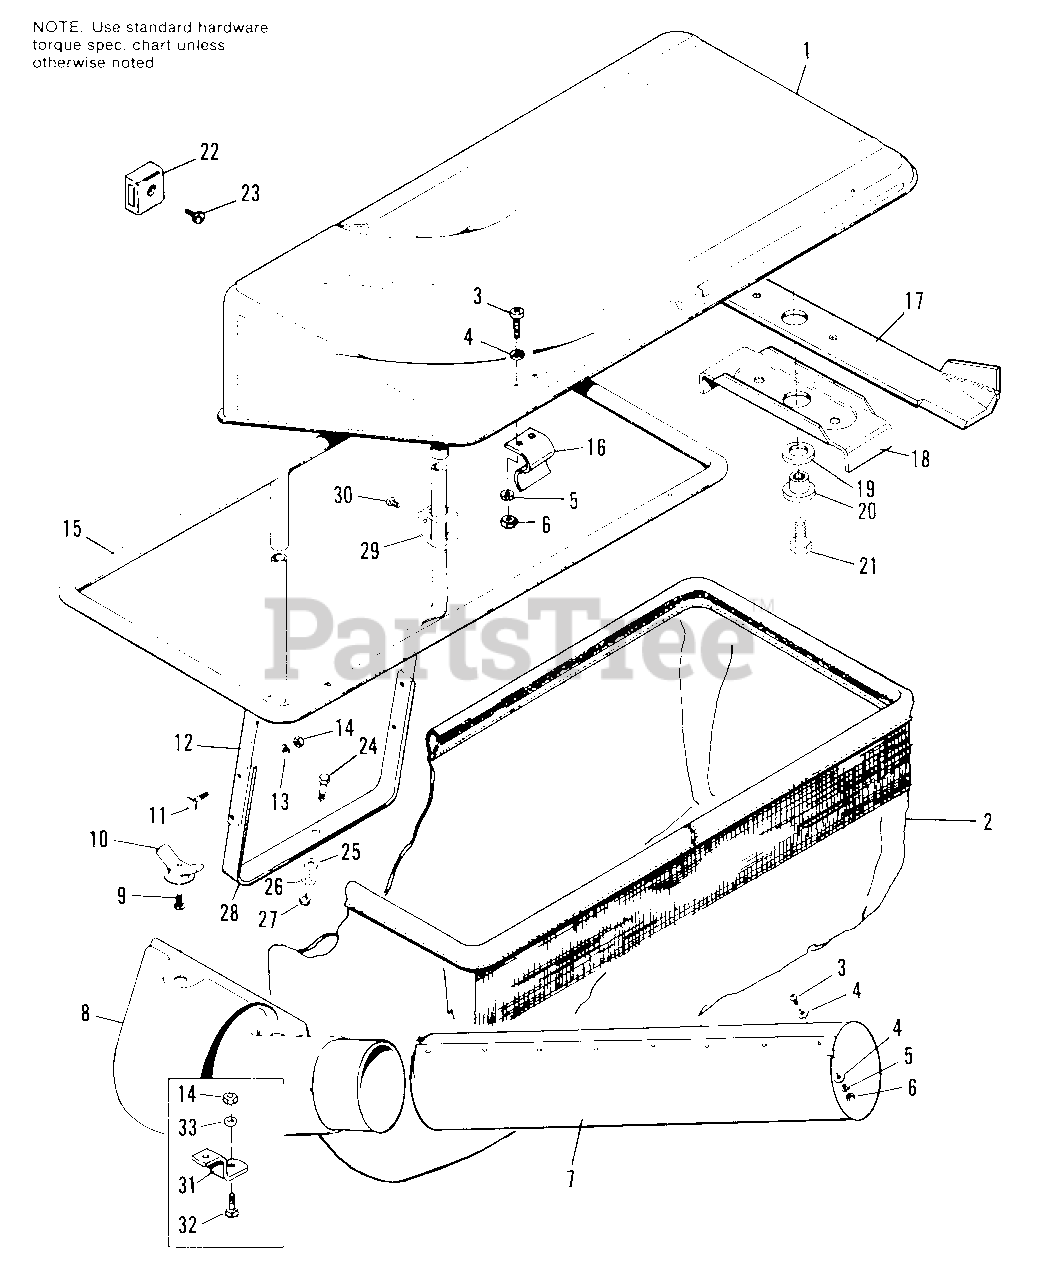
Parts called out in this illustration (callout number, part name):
2	BAG, Grass
3	SCREW, Phillips Hd., #10-32 x 1/2
4	WASHER, Plain, 3/16
5	LOCKWASHER, #10
6	NUT, Hex, Full, #10-32
7	TUBE, Discharge
9	BOLT, Carriage, 5/16-18 x 1
10	NUT ASSY.
11	BOLT, Curved Hd.
12	SUPPORT, Vertical
13	LOCKWASHER, 5/16
14	NUT, Hex, Full, 5/16-18
15	BRACKET, Support
17	*BLADE ASSY.
18	*STIFFENER, Blade
19	*WASHER, Belleville
20	*WASHER, Shoulder
21	*CAPSCREW, Hex Hd., 1/2-20 x 1-1/2 L.H. Thd.
22	*MUFFLER, Deflector
24	*CAPSCREW, Hex Hd., 3/8-16 x 1
25	*WASHER, Plain, 3/8
26	*LOCKWASHER, 3/8
27	*NUT, Hex, Full, 3/8-16
28	*BRACKET, Support
30	*SCREW, Hex, Self Tapping, Taptite, 1/40-20 x 3/8
31	*SUPPORT, Adaptor
32	*BOLT, Carriage, 5/16-18 x 5/8
33	*LOCKWASHER, 5/16
